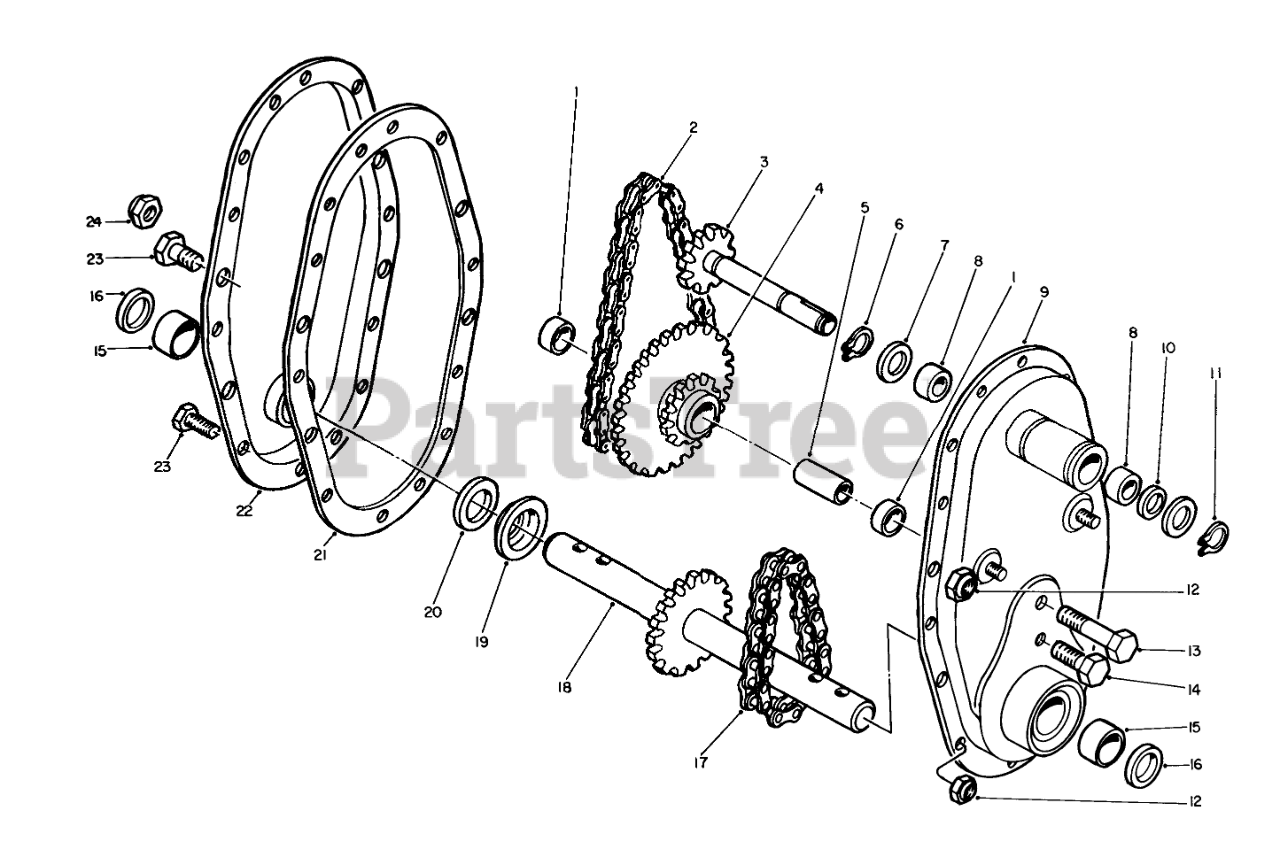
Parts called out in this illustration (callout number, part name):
1	Bearing
2	Upper Chain
3	Input Shaft
4	Sprocket Assembly (Incl.Ref. #1)
5	Idler Sleeve
6	Retaining Ring
7	Washer
8	BEARING-NEEDLE
9	Chain Case Assembly L.H.(Incl. Ref. #8&15)
10	Seal
11	Retaining Ring
12	NUT-LOCK, CONE
13	Capscrew
14	SCREW-HH
15	Bearing
16	Seal
17	Chain-Lower
18	Tine Shaft
19	Spacer Cup
20	Shim-Gear
21	Gasket
22	Chain Case Assembly R.H.(Incl. Ref. #15)
23	SCREW-HH
24	NUT-LOCK, CONE
